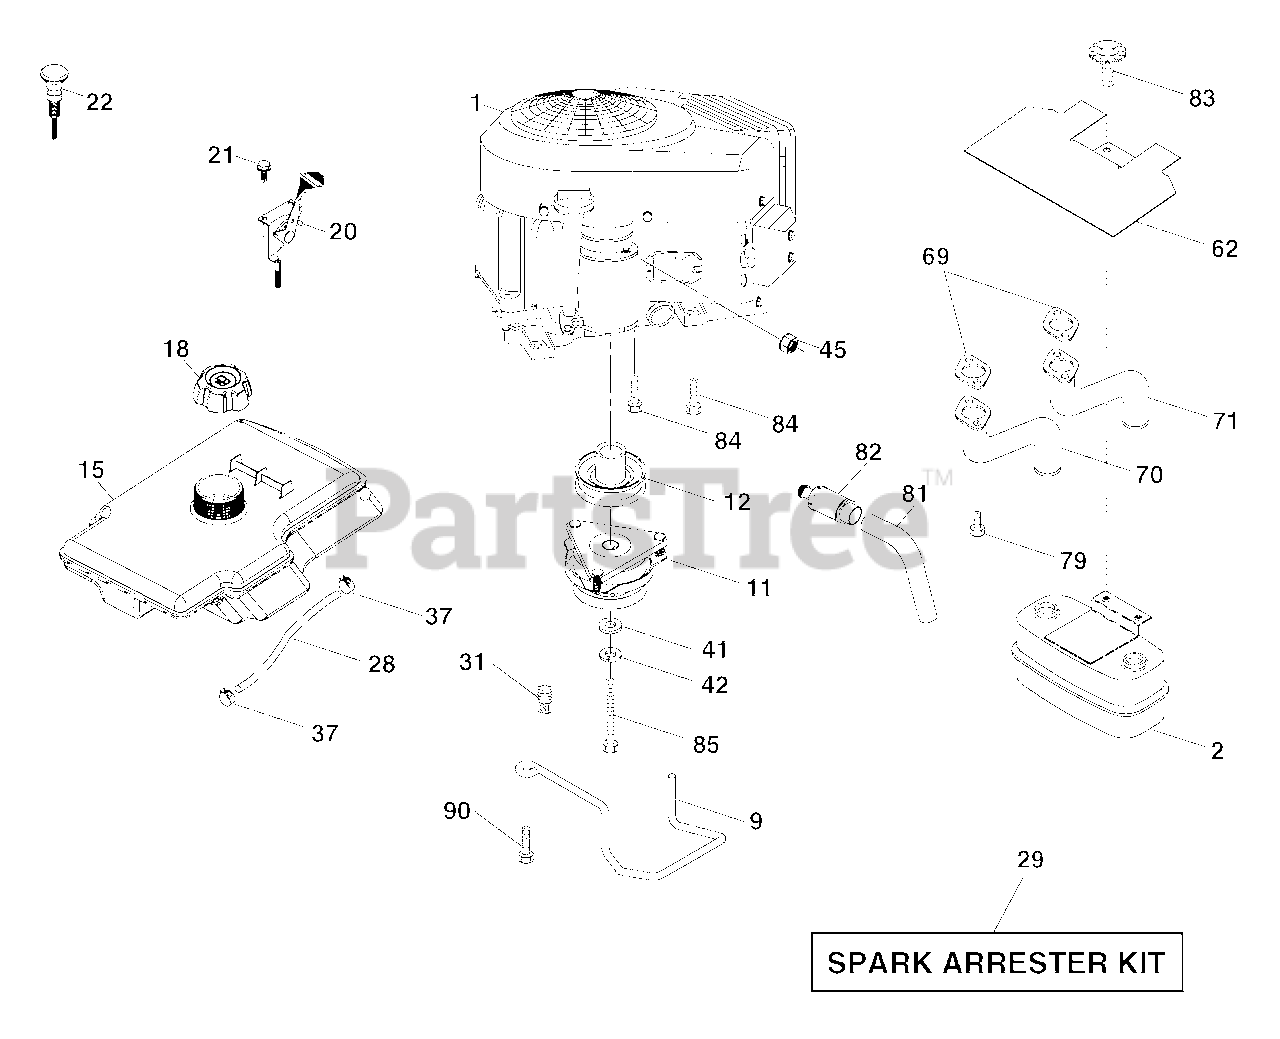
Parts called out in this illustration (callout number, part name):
9	Keeper Belt Engine
11	Clutch Ogura
12	Pulley Engine
15	Tank Fuel
18	Cap Asm
20	Control Throttle
21	Screw 10 x 3/4 Single Lead-Hex
22	Control Choke
28	Fuel Line
29	Spark Arrester Kit
31	Clip Push-In Hinged
37	Clamp Hose
41	Washer 1-1/2 OD x 15/32 ID x .250
42	Washer Lock 7/16
45	Nut Keps Hex 1/4-20 unc
62	Shield Heat Muffler
70	Exhaust Tube LH
71	Exhaust Tube RH
79	Screw Socket Head 5/16-18 x 1
81	Tube Drain Oil Easy
82	Plug Drain Oil
83	Bolt 5/16-18 unc x 1 w/Sems
84	Screw 3/8-16 x 1-1/4
85	Bolt Hex 7/16-20 x 4 x Gr. 5-1.5 Thr
90	Screw 3/8-16 x 1
